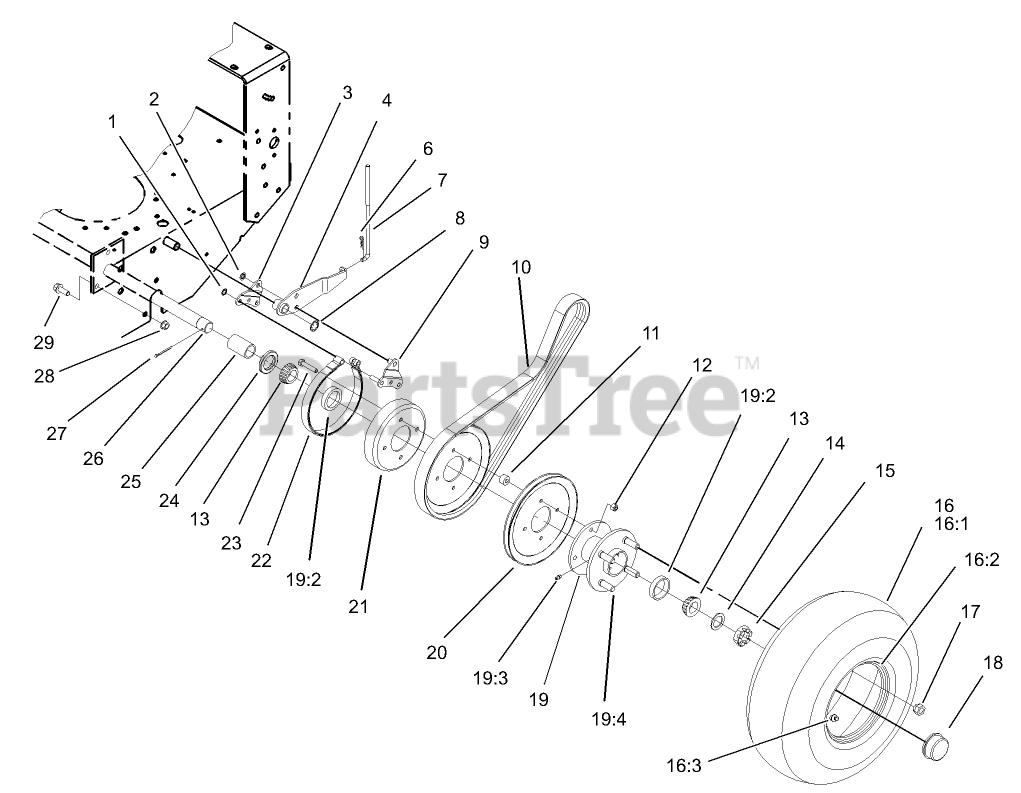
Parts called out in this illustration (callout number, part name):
1	RING-RETAINING
2	RING-RETAINING, EXTERNAL
3	PLATE-LINK, BRAKE
4	BRAKE ARM ASM
6	PIN-COTTER
7	ROD-BRAKE
8	RING-RETAINING
9	BRAKE LINK ASM
10	V-BELT
11	SPACER-PULLEY
12	NUT-LOCK, NI
13	BEARING-CONE, TAPERED
14	WASHER-SPACER
15	NUT-SHH
16	WHEEL AND TIRE ASM
16:2	WHEEL
16:3	STEM-VALVE
17	NUT-LUG
18	CAP-DUST
19	HUB/WHEEL ASM
19:1	Hub-Wheel
19:2	BEARING-CUP, TAPERED
19:3	FITTING-GREASE
19:4	STUD-WHEEL
20	PULLEY-WHEEL
21	DRUM-BRAKE
22	BAND-BRAKE
23	SCREW-HH
24	SEAL-GREASE
25	SPACER-WHEEL
26	AXLE ASM
27	PIN-COTTER
28	NUT-HF
29	SCREW-HHF
